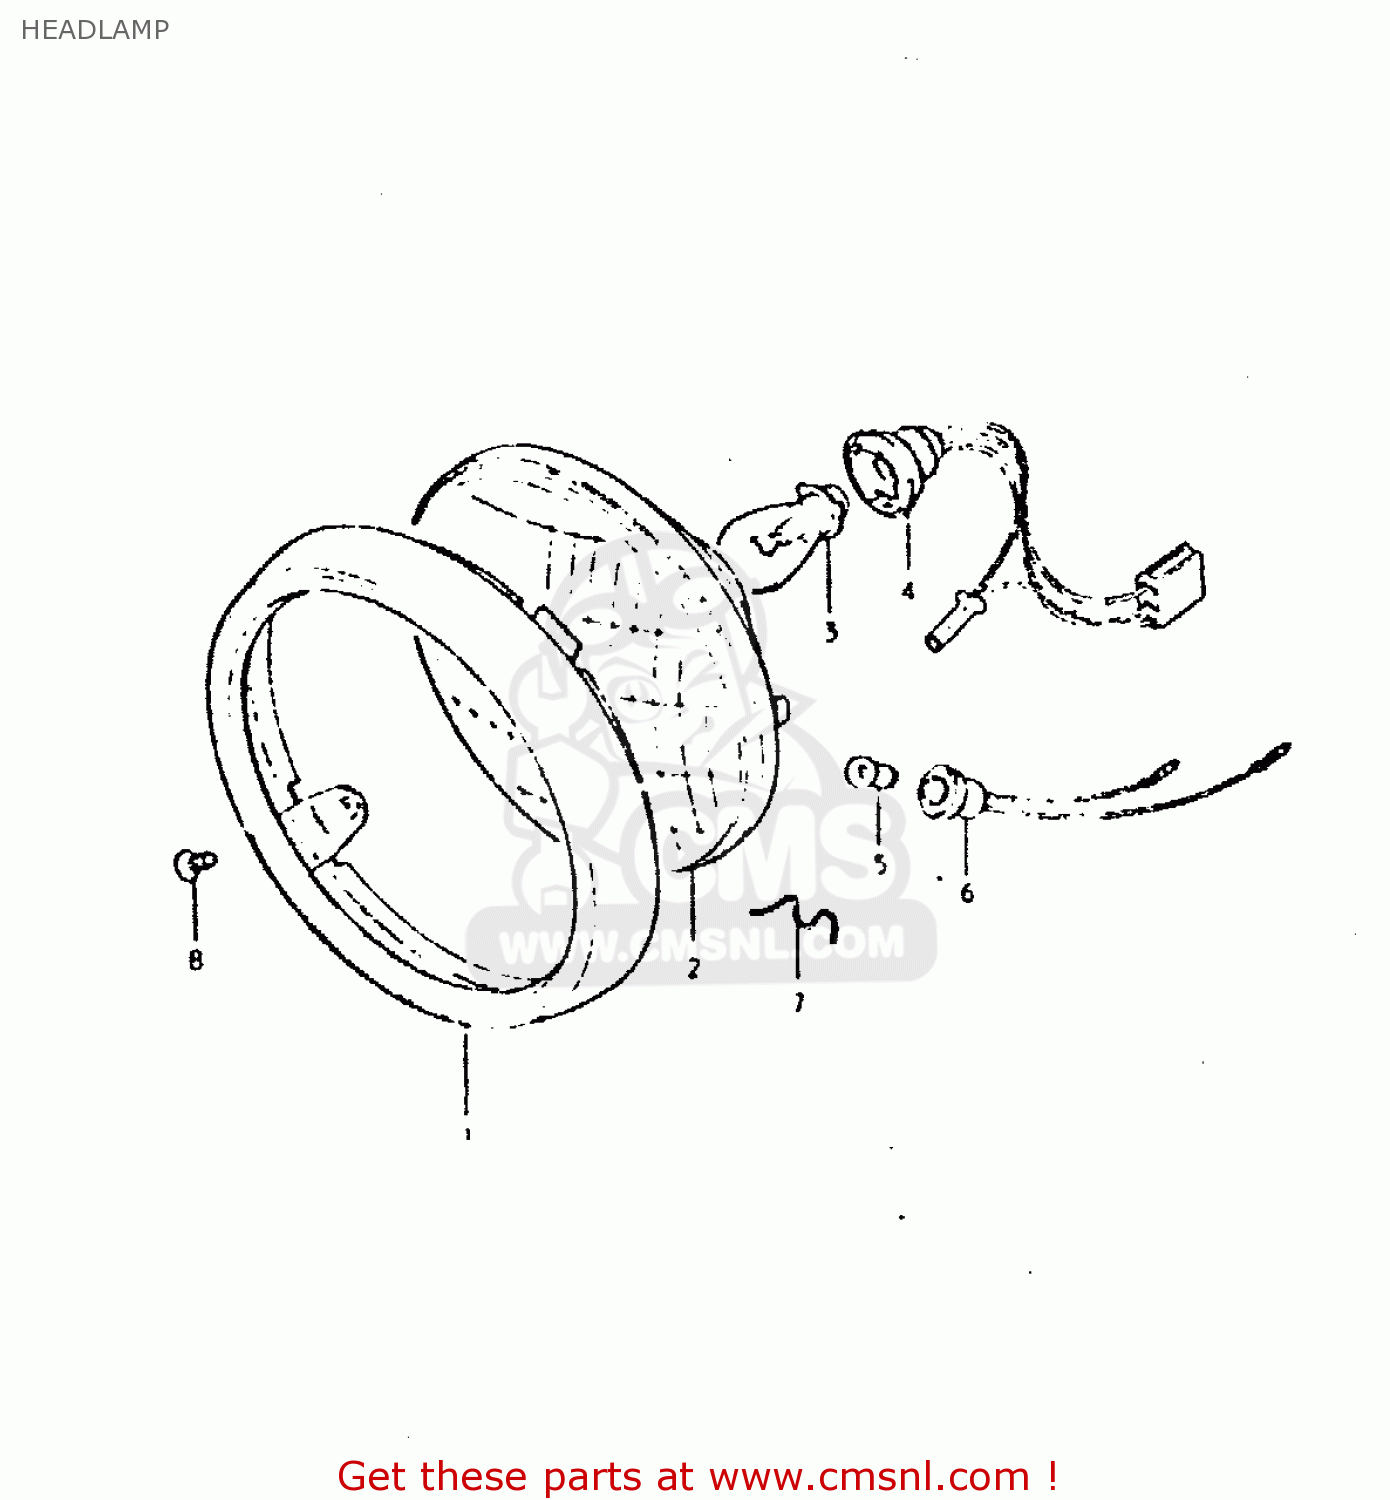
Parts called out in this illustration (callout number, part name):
1	RIM
2	LAMP UNIT
3	BULB
4	SOCKET
5	BULB(12V3.4W,STANLEY,A72A)
6	SOCKET
7	SPRING
8	SCREW
